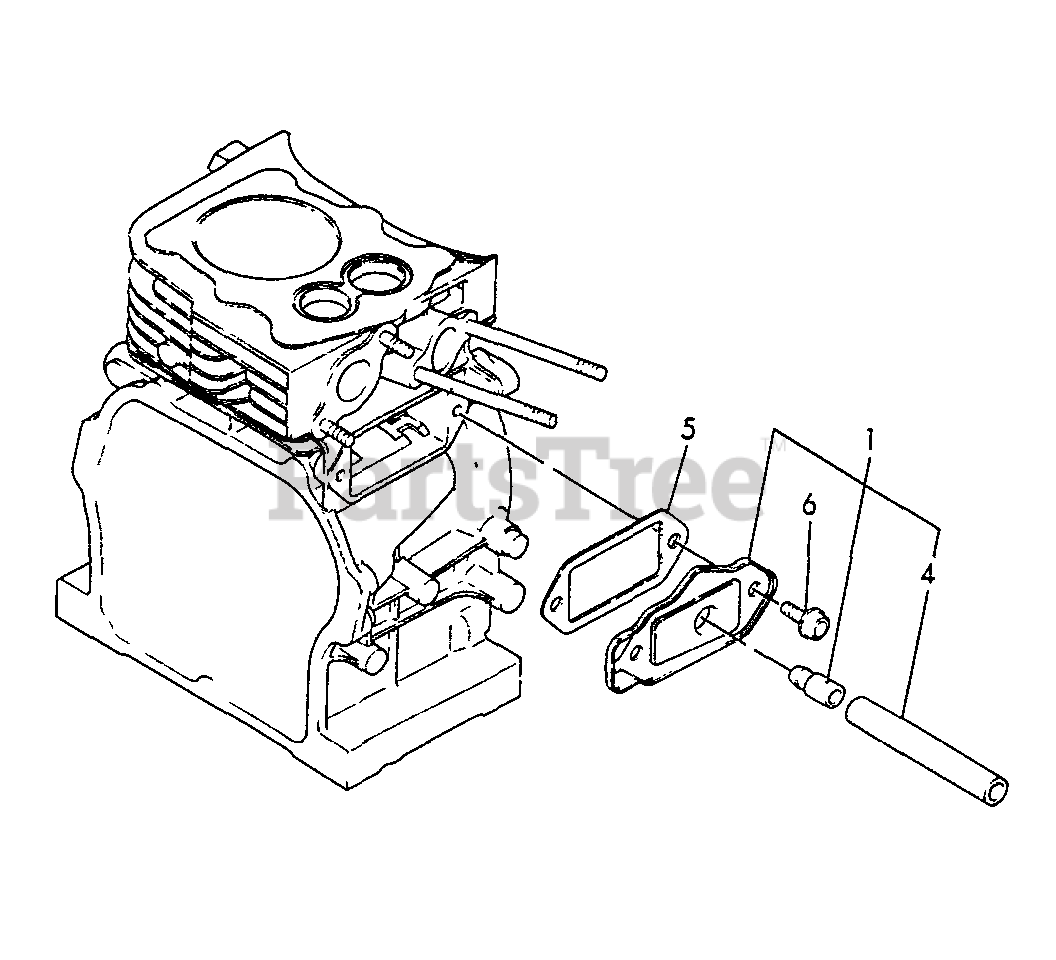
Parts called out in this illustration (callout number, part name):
1	VENT, FUEL TANK
4	PIPE - BREATHER
5	GASKET
6	BOLT - 6X8 -- PLATED
